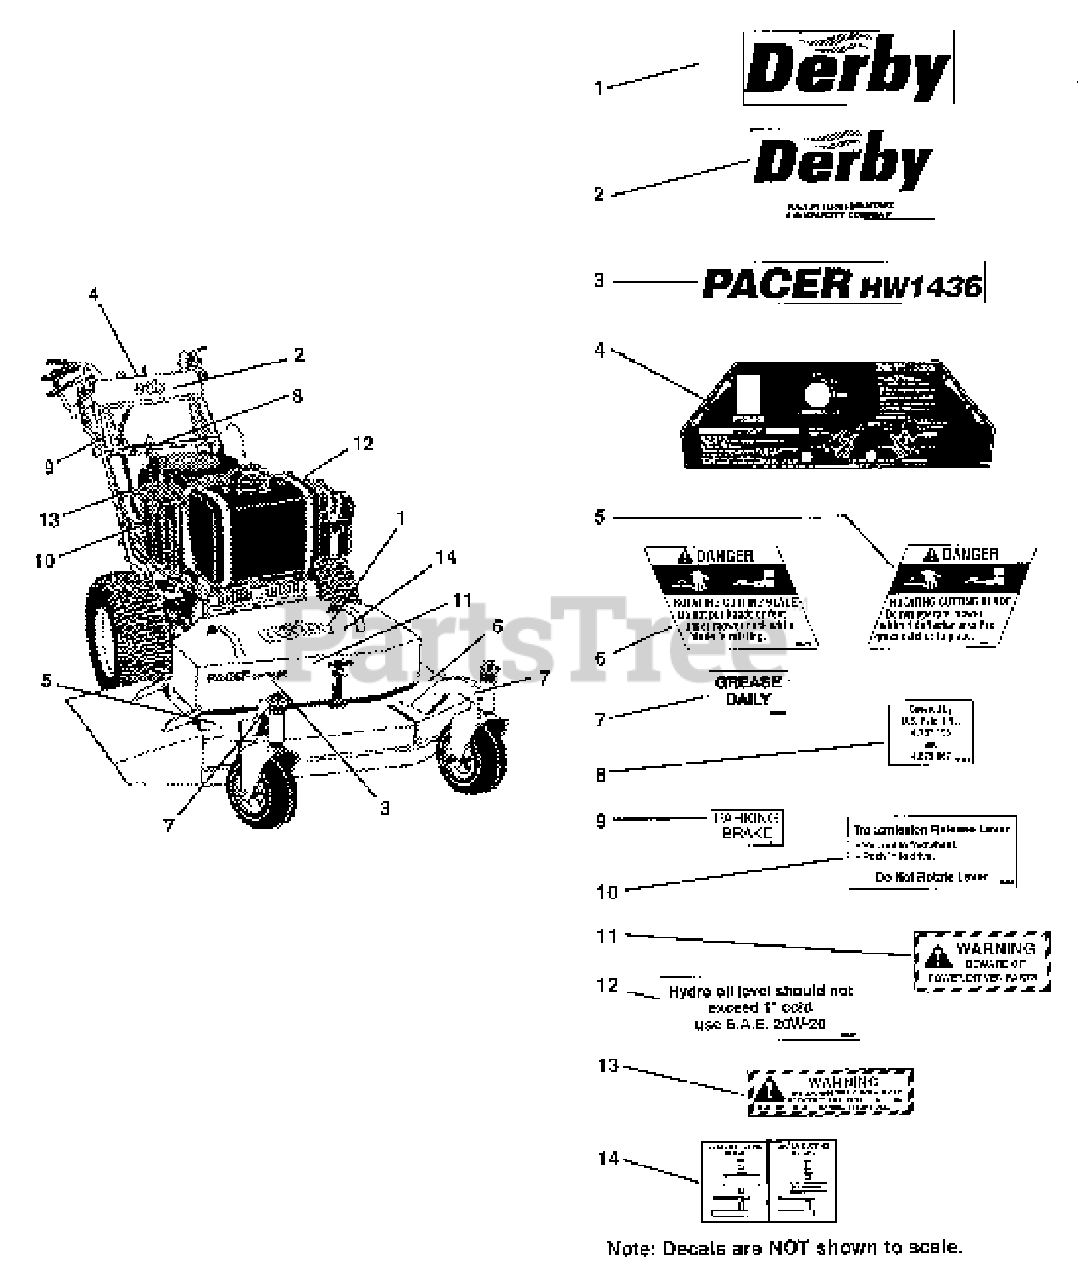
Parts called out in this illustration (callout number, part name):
1	DECAL, Derby Logo
2	DECAL, Derby Built By Ferris
3	DECAL, Pacer
4	DECAL, Pacer Operation
5	DECAL, Danger (Chute In Place)
6	DECAL, Danger (Hand Under Deck)
7	DECAL, Grease Daily
8	DECAL, Patent
9	DECAL, Parking Brake
10	DECAL, Transmission Release
11	DECAL, Warning (Located under mower guard)
12	DECAL, Oil Level (Located above oil reservoir)
13	DECAL, Warning
14	DECAL, Pulley Position (Located under mower guard)
